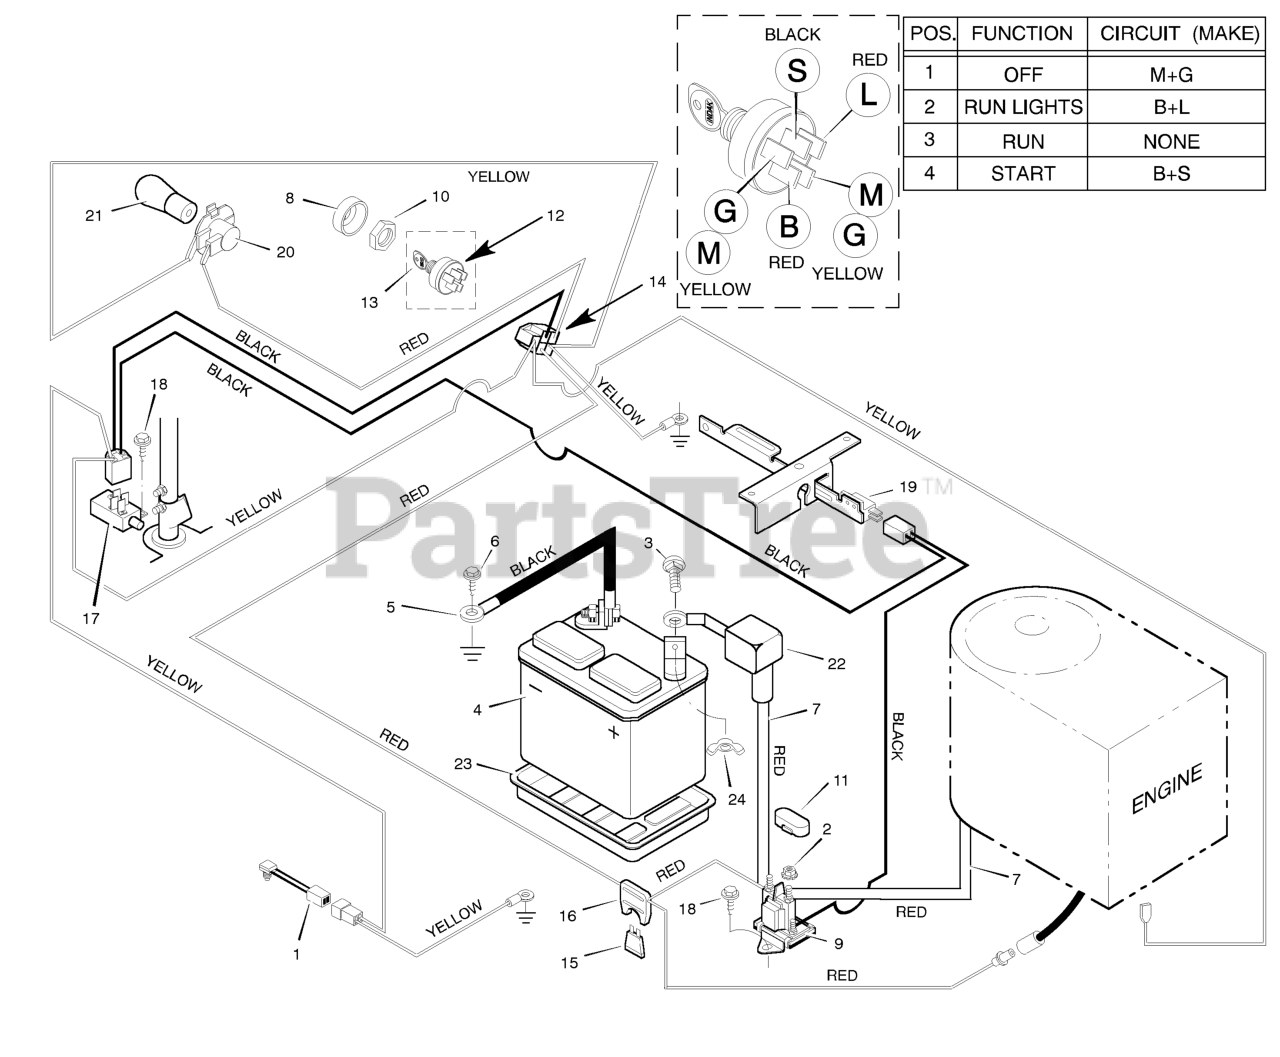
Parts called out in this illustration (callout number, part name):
1	Switch, Seat Sensor
2	Locknut
3	Bolt
4	Battery
5	Cable, Battery Ground
7	Cable, Red Battery
8	Cap, Ignition
9	Solenoid
10	Nut, Hex
11	Cover, Solenoid
12	Switch, Ignition
13	Key, Ignition
14	Harness, Chassis Wire
16	Holder, Fuse
17	Switch, Limit
19	Switch, Limit
20	Socket, Light
21	Bulb, Light
22	Cover, Terminal
23	Tray, Battery
24	Wingnut
